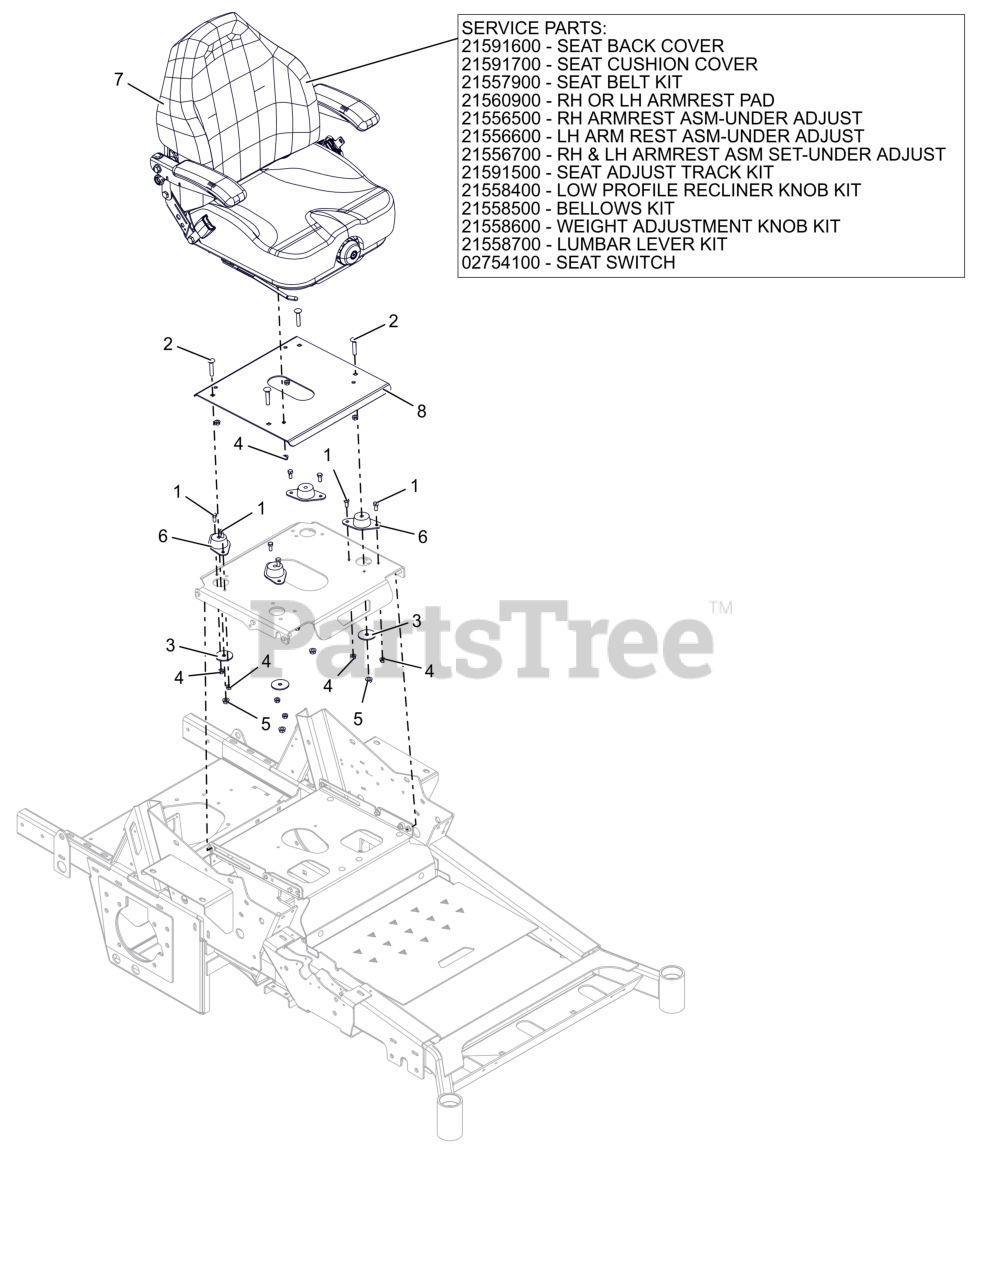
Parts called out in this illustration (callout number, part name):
1	BLT,HEX .31-18X.75 G5 ZCC
2	BLT, RHSN .38-16X2.00 G5 ZCC
3	WSHR-FL-STL 0.406X2X0.125 ZCC
4	NUT,LK-CTR-FLG .31-18 GF ZCC
5	NUT-LK-CTR-FLG .375-16 GF ZCC
6	MOUNT, FAIL-SAFE COMPRESSION
7	SEAT- FULL SUSPENSION
7	SEAT BACK COVER
7	SEAT CUSHION COVER
7	KIT, SEAT BELT
7	PAD, ARMREST RH OR LH (HARD)
7	ARMREST, RH ASSEMBLY
7	ARMREST, LH ASSEMBLY
7	SET, RH & LH ARMREST ASSEMBLY
7	SETA ADJUST TRACK KIT
7	KIT, LOW PROFILE RECLINER KNOB
7	KIT, BELLOWS
7	KIT, WEIGHT ADJUSTMENT KNOB
7	KIT, LUMBAR LEVER
7	SWITCH- SNAP MTG N.O.
8	PLATE- SEAT MOUNTING
